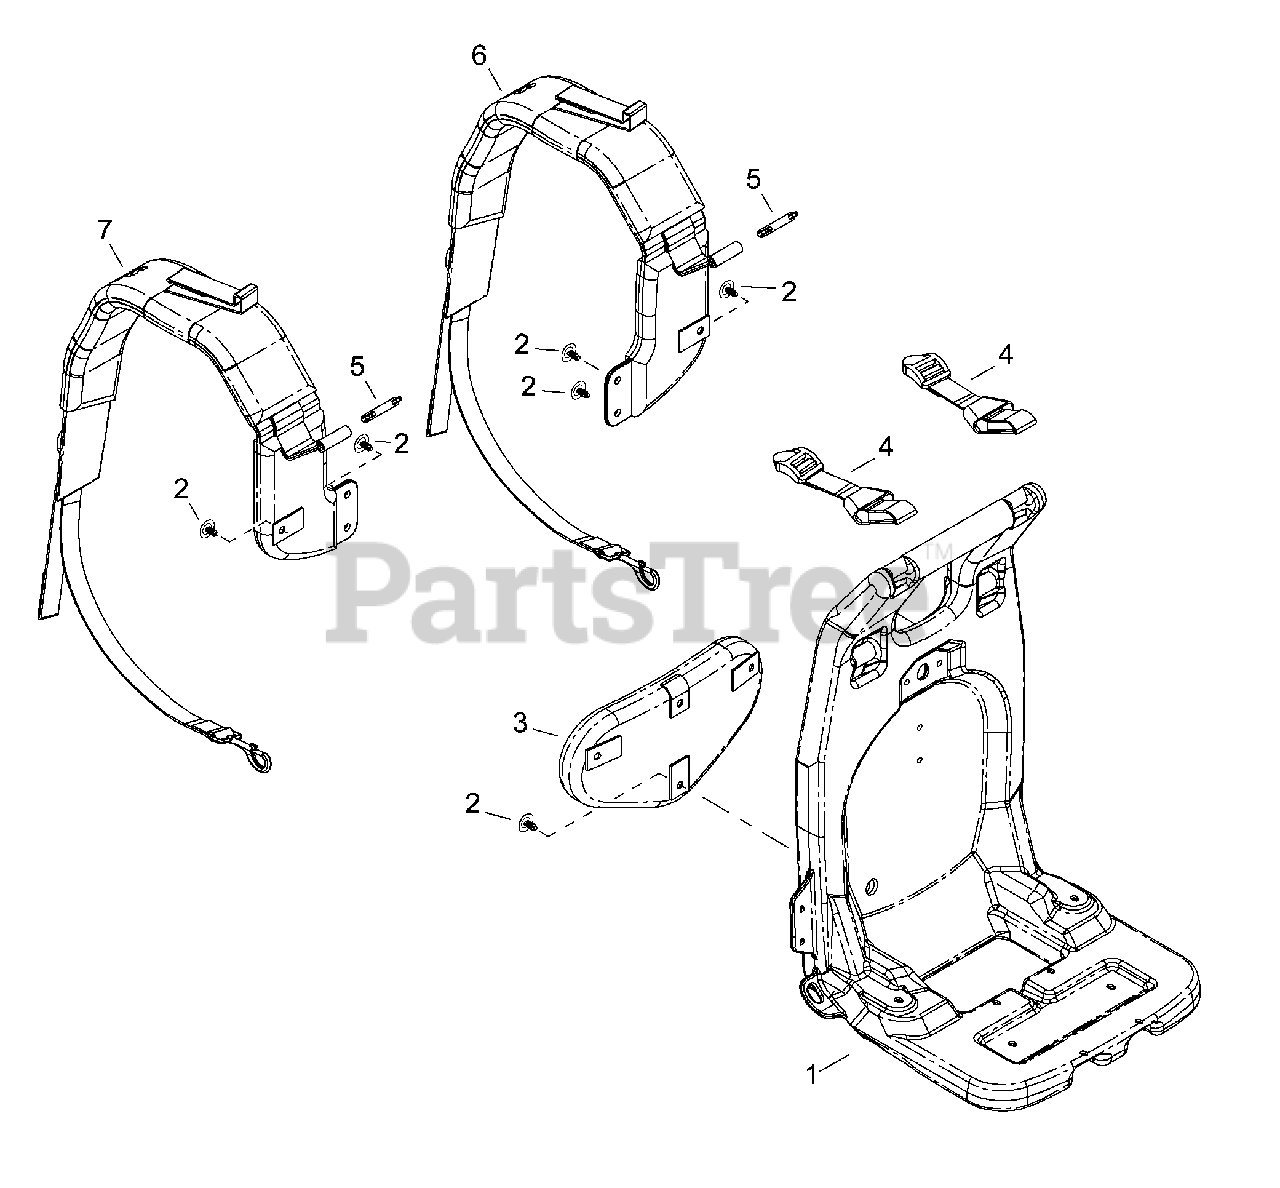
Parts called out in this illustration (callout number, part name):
1	FRAME, BACKPACK
2	CLIP
3	CUSHION, BACKPACK
4	CONNECTOR, STRAP
5	RING, HARNESS
6	HARNESS - RIGHT
7	HARNESS - LEFT
